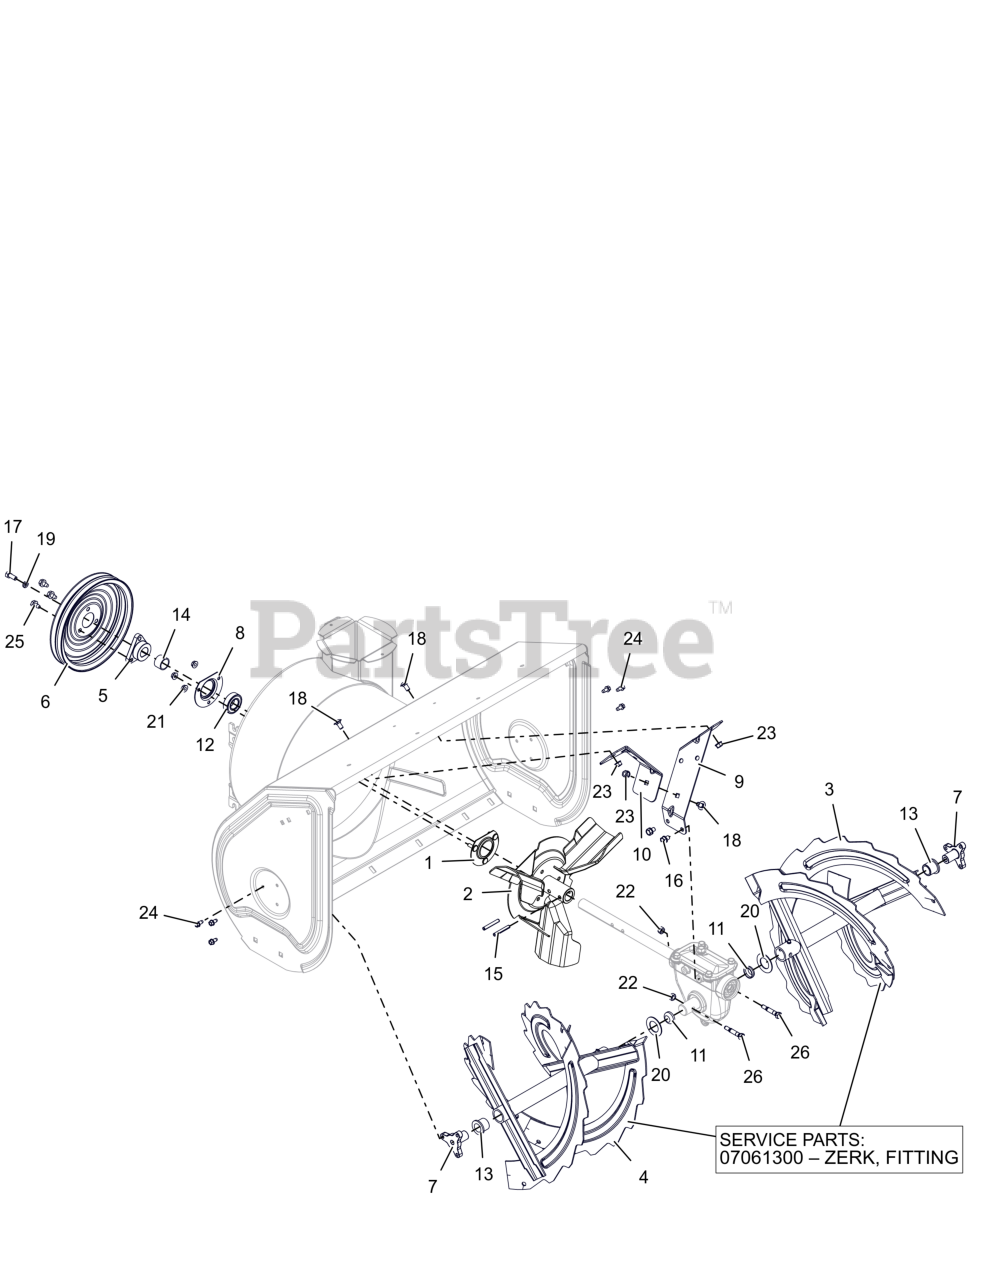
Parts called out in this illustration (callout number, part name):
1	BEARING FLANGE
2	IMPELLER, 3 BLADE-14"
3	RAKE, LH W/ZERK - 30"
4	RAKE, RH W/ZERK - 30"
5	PULLEY HUB, D-BORE .87 PRO
6	PULLEY, SPIN FORM DUAL GROOVE
7	SUPPORT, RAKE BUSHING
8	BEARING FLANGE
9	BRACKET, GEARCASE SUPPORT - LH
10	BRACKET, GEARCASE SUPPORT - RH
11	PLUG, RAKE TUBE
12	BRG-BALL .876 X 1.750 X .50
13	BSHG-FLG, NY.778 ID X 1.018 OD
14	BSHG,SPCR .895X1.065X.693
15	PIN-ROLL .250X1.75
16	BLT, SEMS .31-18X.50 G5 ZCC
17	BLT, HEX .31-24X.750 G5 ZCC
18	BLT,RHSSN.31-18X.625 G5 ZCCP30
19	WSHR, LK-HVY .312X.097 ZCC
20	WSHR- FLT 1.010X1.755X.062 ZCC
21	NUT-LK-CTR-FLG .25-20 ZC120
22	NUT,LK-CTR .31-18 GA ZCC
23	NUT-LK-TOP-FLG .312-18 GF ZCC
24	SCR-TAP .25-20X.50 HWH ZCC
25	SCR,TAP .312-18X.50 HWH TR ZCC
26	SHEAR BOLT SERVICE ASSEMBLY (INCLUDES NUT)
